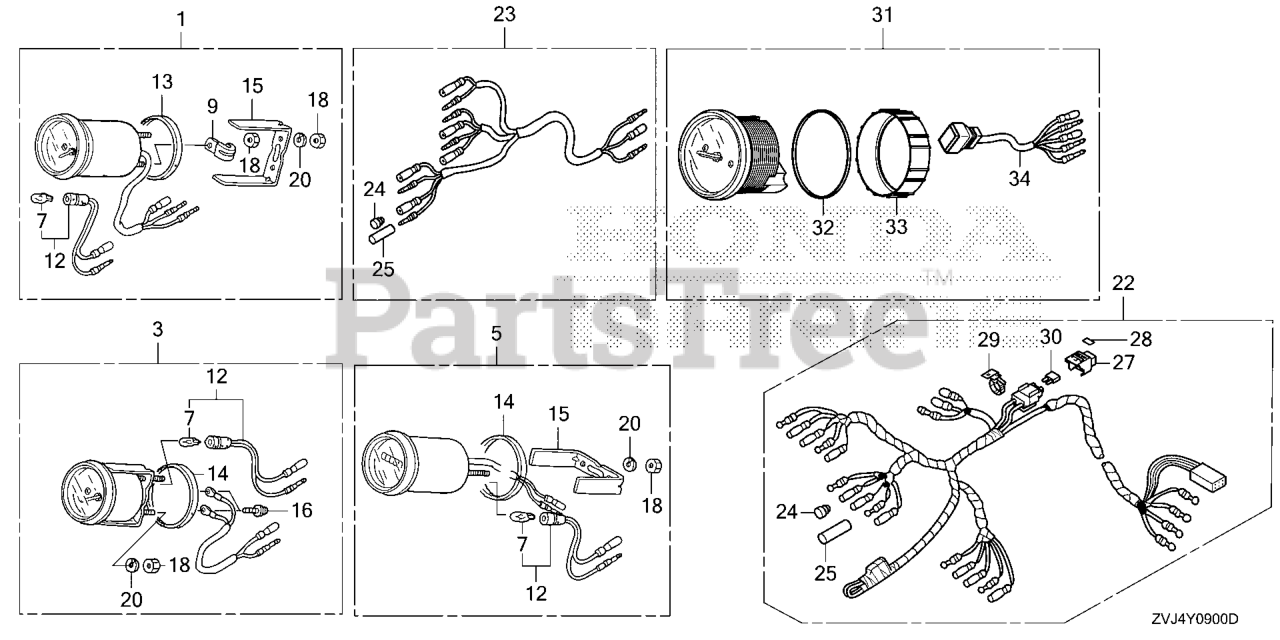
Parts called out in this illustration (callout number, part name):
31	TACHO METER KIT
32	CUSHION RUBBER
33	RING
34	WIRE ASSY.
